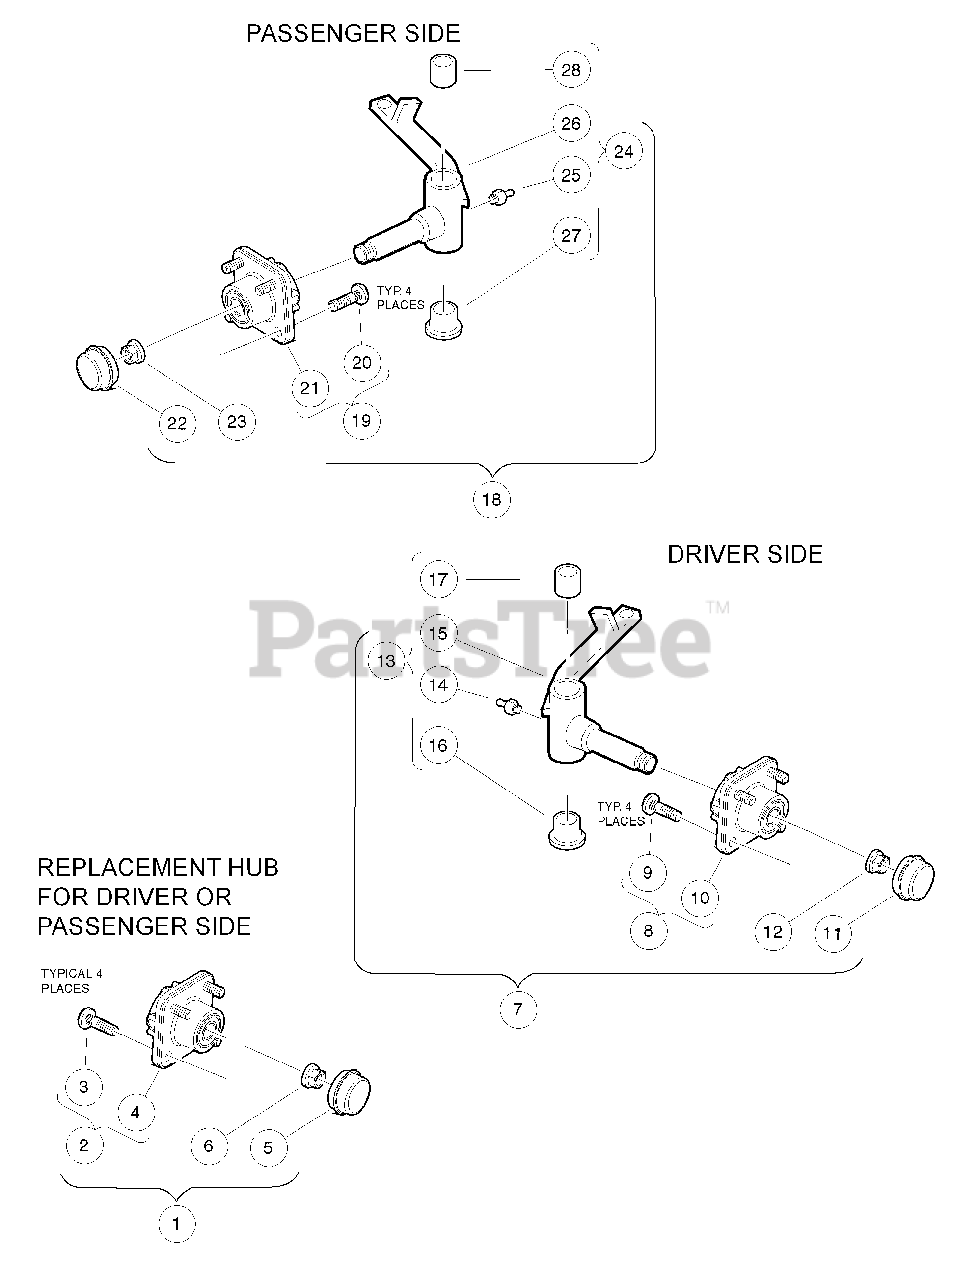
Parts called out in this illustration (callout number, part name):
1	Replacement Kit, Front Hub
2	Front Hub Assembly, Ball Bearing
3	Lug Stud, 1/2-20 UNF, 4037 Stl
4	Hub, Front
5	Cap, Front Hub
6	Hex Nut, Locking Flange, M14x2
7	Asm, Hub And Spindle, Left-Hand Ext
8	Front Hub Assembly, Ball Bearing
9	Lug Stud, 1/2-20 UNF, 4037 Stl
10	Hub, Front
11	Cap, Front Hub
12	Hex Nut, Locking Flange, M14x2
13	Asm, Spindle, LH, Ext
14	Fitting, 1/4-28 Thread-Forming Grease
15	Subasm, Spindle, LH, Ext
16	Bushing, Flanged Bronze
17	Bushing, Bronze Spindle
18	Asm, Hub And Spindle, Right-Hand Ext
19	Front Hub Assembly, Ball Bearing
20	Lug Stud, 1/2-20 UNF, 4037 Stl
21	Hub, Front
22	Cap, Front Hub
23	Hex Nut, Locking Flange, M14x2
24	Asm, Spindle, RH, Ext
25	Fitting, 1/4-28 Thread-Forming Grease
26	Subasm, Spindle, RH, Ext
27	Bushing, Flanged Bronze
28	Bushing, Bronze Spindle
